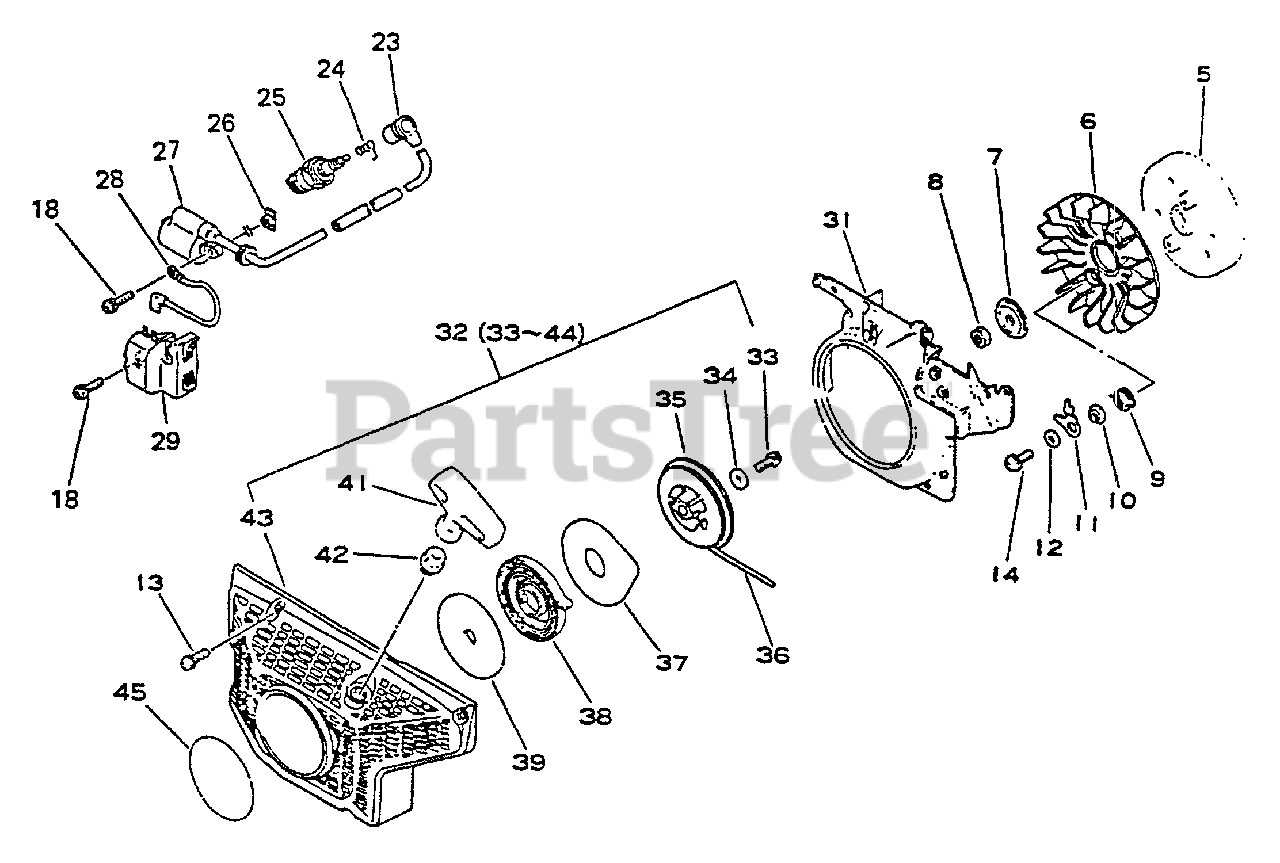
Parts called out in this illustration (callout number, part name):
5	FLYWHEEL
7	WASHER - CUP
9	SPRING, RETURN
11	PAWL, STARTER
12	WASHER - 5
13	SCREW - 5X20
14	SCREW - 5X14
18	SCREW - 4X20
23	CAP, SPARK PLUG
24	TERMINAL, SPARK PLUG CAP
25	SPARK PLUG -- CJ-6Y
27	COIL, IGNITION
29	COIL, IGNITION
31	SHIELD, FAN
32	STARTER ASSY
33	SCREW - 5X14
34	WASHER - 5
35	REEL, ROPE
36	ROPE, STARTER - 4X950
37	PLATE, STARTER
38	SPRING, REWIND
39	PLATE, STARTER
41	GRIP, STARTER
42	GUIDE, ROPE
43	CASE, STARTER
45	LABEL - ECHO
